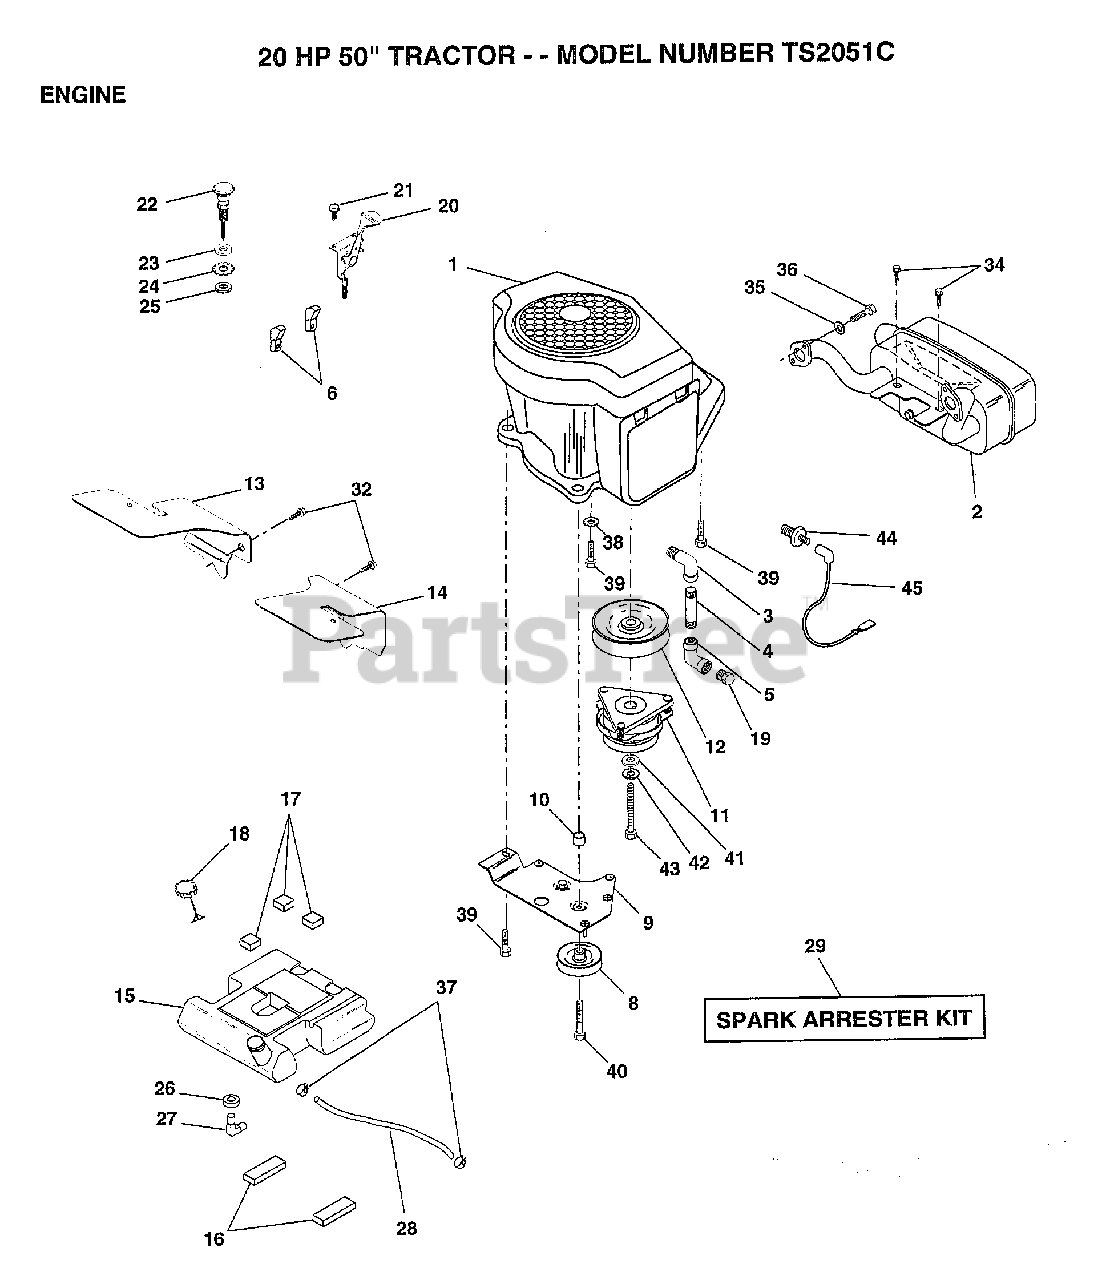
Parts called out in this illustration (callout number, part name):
1	ENGINE KOHLER MODEL NO. MV20
2	MUFFLER.KOH.VCT.
3	STREET ELBOW LT
4	PIPE NIPPLE
5	ELBOW
6	CLAMP.TUBE.DBL.EN
10	BUSHING.
12	PULLEY.ENGINE.VGT
13	BAFFLE.AIR.LH.K
16	PAD IDLER TI
17	PAD-SPACER LT
18	CAP ASM FUEL
19	PLUG T
20	CONTROL THTL 37
21	SCREW LT
22	"CONTROL.CHOKE.51"""
23	WASHER
24	LOCKWASHER
26	BUSHING OUTLET T
27	STEM.TANK.FUEL
29	SPARK ARREST KIT
32	SCREW LT
34	SCREW
35	LOCKWASHER
36	SCREW
37	HOSE CLAMP
38	LOCKWASHER
39	SCREW LT
40	SCREW.3/8-16X3.25
41	WASHER
42	LOCKWASHER
44	SWITCH OIL KOHLER
45	WIRE LEAD KOHLER
